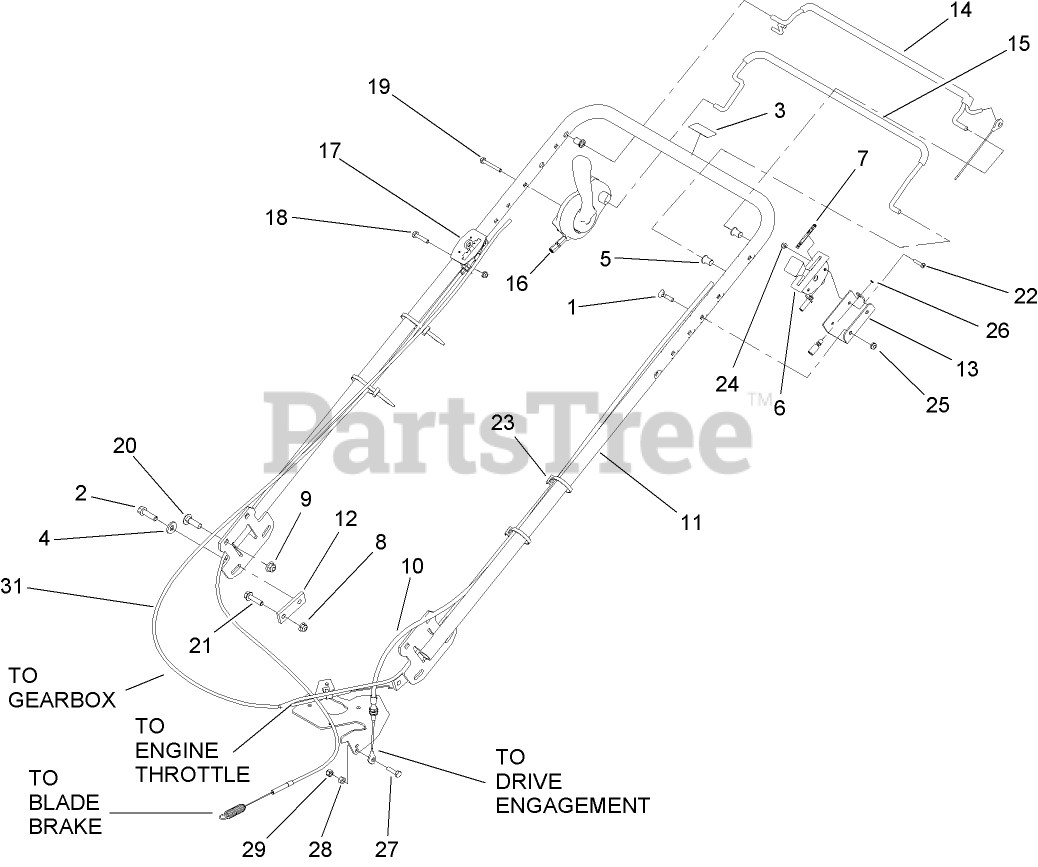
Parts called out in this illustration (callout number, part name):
1	BOLT-HANDLE
2	SCREW-TAPTITE
3	DECAL-PROTECTION, EAR
4	WASHER-BELLEVILLE
5	BUSHING
6	CONTROL-THROTTLE
7	DECAL-THROTTLE / CHOKE
8	NUT-HF, NI
9	NUT-HF, NI
10	CABLE-TRACTION
12	NUT-HANDLE
13	BRACKET-CONTROL
14	BAIL-TRACTION
15	BAIL-BBC (WITH GRIP)
16	CONTROL-BBC
17	CONTROL-SHIFT
18	SCREW-HH
19	SCREW-HH
20	BOLT-CARR
21	SCREW-HHF
22	SCREW-PPH
23	TIE-CABLE
24	NUT-LOCK, NI
25	NUT-LOCK, NI
26	E-RING
27	SCREW-HH
28	NUT-HEX
29	NUT-LOCK, NI
31	CABLE-SHIFTER
